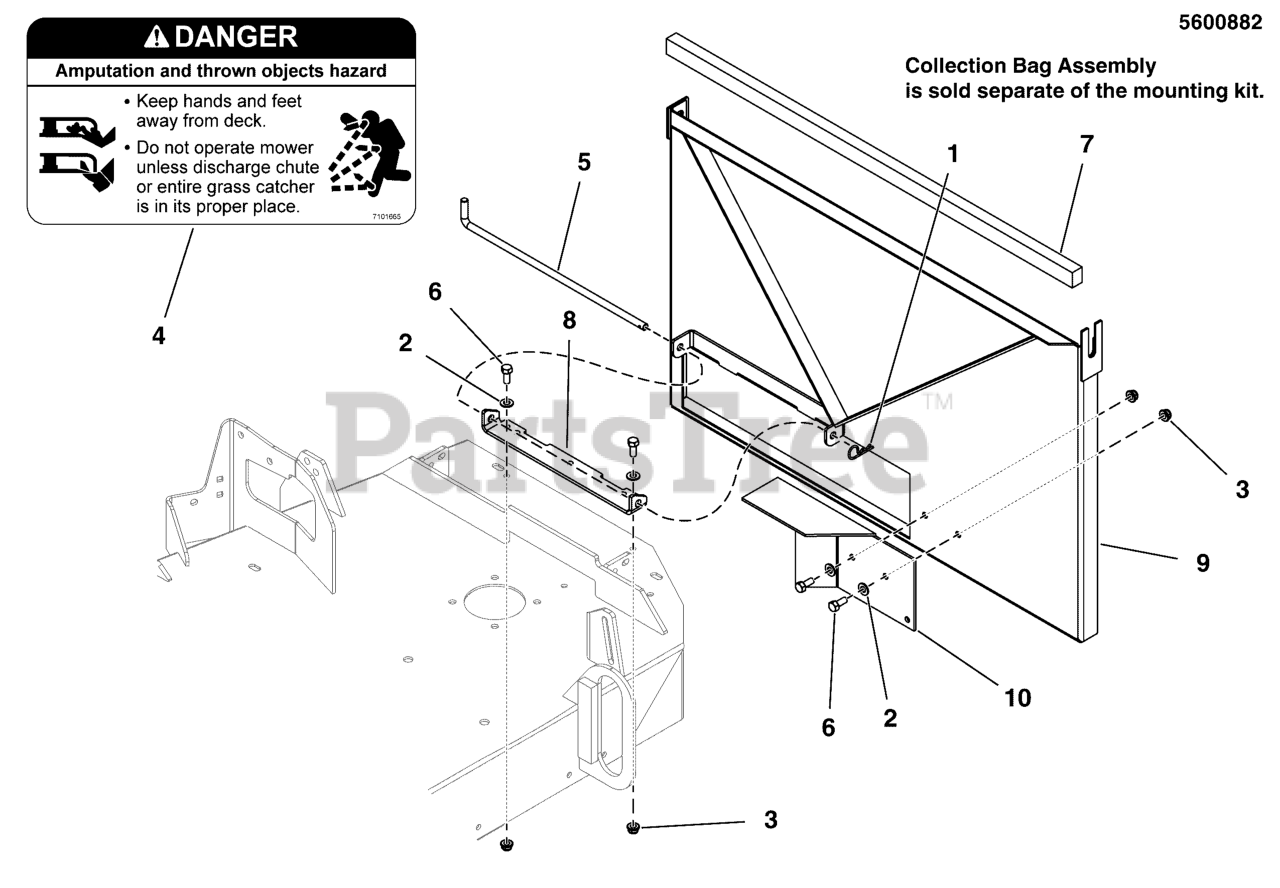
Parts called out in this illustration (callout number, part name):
1	PIN, HAIR, .0915 X 1-7/8
2	WASHER, 5/16" SAE
3	NUT, 5/16-18 HEX NYLOCK FLANGE
4	DECAL, DANGER DO NOT OPERATE W/O DEFLECT
5	ROD, BAGGER MOUNT, 48/52"
6	BOLT, 5/16-18 X 3/4 GD5
7	FOAM, 3/4 X 1 X 30.50
8	PLATE, BAGGER MOUNT BRACKET, iCD DECK
9	WELD, BAGGER MOUNT, 52" EVO ICD DECK
10	WELD, DEFLECTOR, BAGGER - BLK
